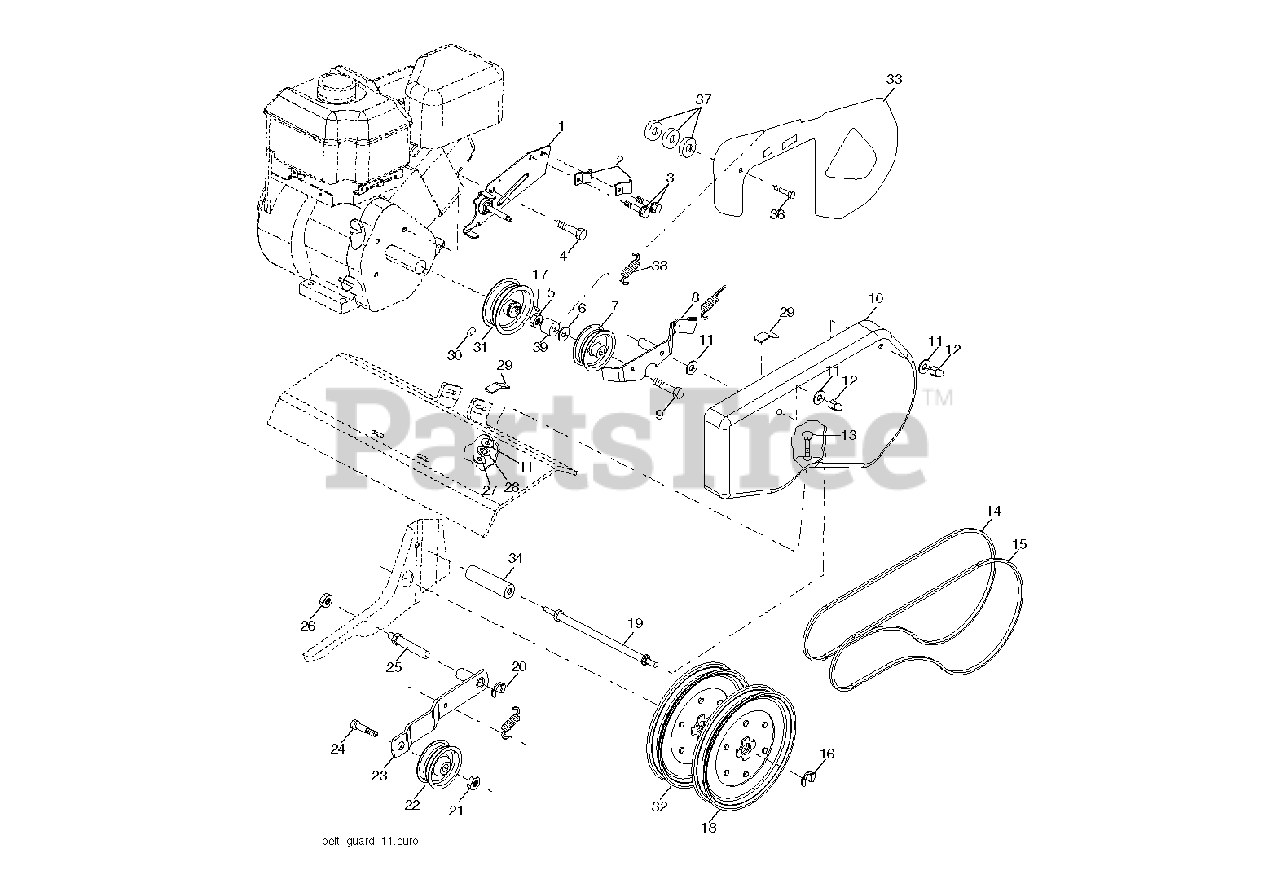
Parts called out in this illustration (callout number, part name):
1	RP BRKT.ASM.GUARD.BELT
2	CONDUIT CLIP T
3	TAPPING SCREW
5	LOCKNUT
7	PULLEY
8	ARM
9	BOLT
11	WASHER
12	CAP
15	BELT
16	RETAINING RING LT
18	SHEAVE,TRANS."D"
19	BOLT.BELT.GUARD
20	KLIP RING TI
21	NUT
22	PULLEY, IDLER
23	ARM, IDLER
25	SHAFT.IDLER.TILLER
26	JAM NUT TI
27	NUT
28	LOCKWASHER
29	PAD IDLER TI
32	SHEAVE.TRANS
37	WASHER
38	SPRING.EXTENSION
